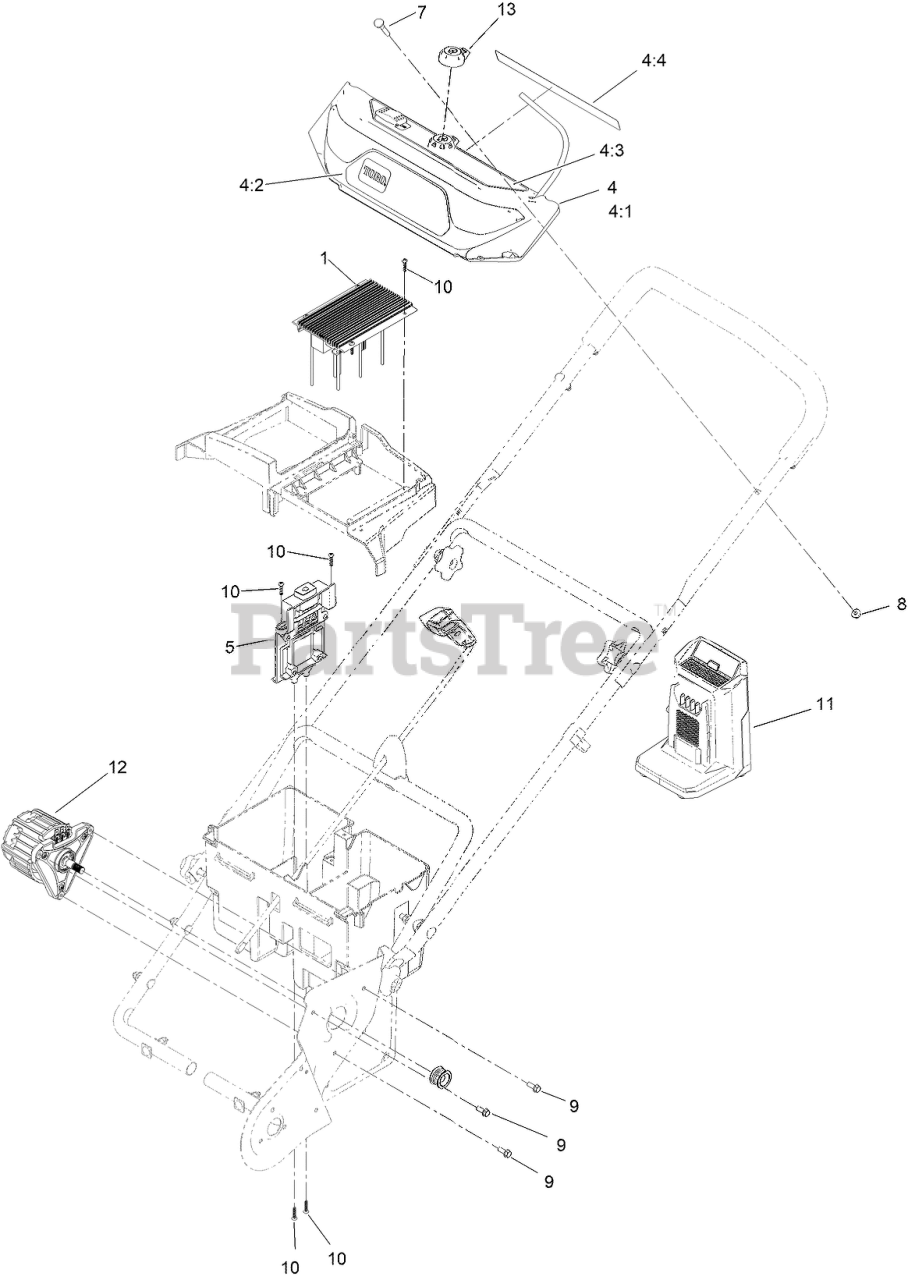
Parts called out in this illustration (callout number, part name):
1	MOTOR-DRIVER, SNOW (60V)
4	DASH PANEL ASM W/DECALS
4:1	DASH PANEL ASM
4:2	DECAL-POWER CLEAR
4:3	DECAL-OPERATION
4:4	DECAL-CAUTION
5	BATTERY TRACK ASM
7	SCREW-HANDLE
8	NUT-HF
9	SCREW-HWH
10	SCREW-PPH
11	CHARGER-60V (2A)
12	MOTOR ASM
13	KEY-BAIL
